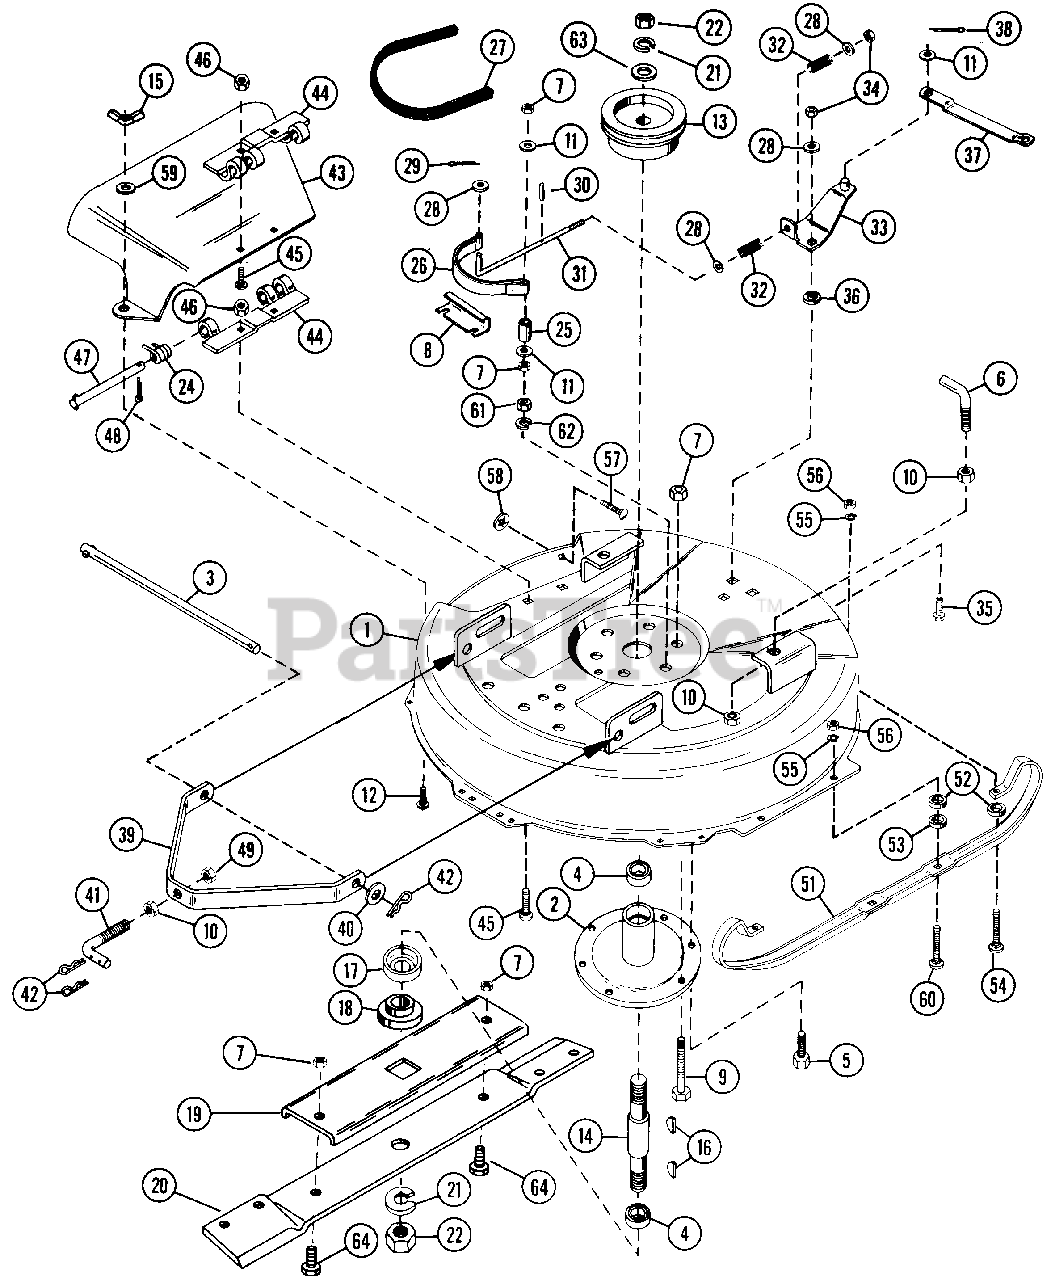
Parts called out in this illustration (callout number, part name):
1	32 INCH MOWER DECK
2	SPINDLE HOUSING
3	TOW PIN
4	RADIAL BEARING
5	BOLT, HEX 3/8-16X.75
6	HANGER HOOK
7	NUT, LOCK 3/8-16
8	BRAKE BAND SUPPORT
9	BOLT, HEX 3/8-16X3.00
10	NUT, JAM 1/2-13 HEX
11	WASHER, FLAT .406X.812X.065
12	BOLT, CARRIAGE 5/16-18X.75
13	MOWER SHEAVE
14	SPINDLE SHAFT
15	NUT, WING 5/16-18 TYPE B
16	KEY, WOODRUFF .187X.75 #9
17	BEARING SLINGER
18	RETAINER HUB
19	BLADE TRAY
20	MOWER BLADE, 32"
21	WASHER, LOCK 3/4 SP
22	NUT, JAM 3/4-10 HEX
24	SPRING, TORSION .37 I.D.
25	SPACER
26	BRAKE BAND
27	V-BELT
28	WASHER, FLAT .312X.734X.065
29	PIN, COTTER .06X.50
30	PIN, SPRING .125X1.000
31	BRAKE ROD
32	SPRING
33	BRAKE ACTUATOR
34	NUT, LOCK 5/16-18
35	BOLT, HEX 5/16-18X.75
36	SPACER
37	STRAP
38	PIN, COTTER .125X1.00
39	MOWER STRAP
40	WASHER, FLAT .531X1.062X.095
41	TOW HOOK
42	HAIR PIN, INTERNAL
43	CHUTE DEFLECTOR
44	HINGE PLATE
45	BOLT, 1/4-20X.625 RD HD SQ NK
46	NUT, LOCK 1/4-20
47	HINGE PIN
48	PIN, COTTER .09X.75
49	NUT, LOCK 1/2-13
51	32 INCH ADJUSTABLE SKID
52	SPACER
53	SPACER BUSHING
54	BOLT, 5/16-18X1.75 RD HD SQ NK
55	WASHER, LOCK 3/8 SP HEAVY
56	NUT, HEX 5/16-18
57	BOLT, 5/16-18X.625 RD HD SQ NK
58	NUT, PUSH 5/16
59	WASHER, FLAT .313X.875X.065
60	BOLT, 5/16-18X1.25 RD HD SQ NK
61	NUT, HEX 3/8-16
62	WASHER, LOCK 3/8 REG.
63	WASHER, FLAT .938X1.750X.134
64	BOLT, HEX 3/8-16X1.00
NS	DECAL, DANGER FOOT
NS	DECAL, NO STEP
NS	DECAL, CAUTION
NS	DECAL, WARNING EYE
NS	DECAL, DANGER HAND
